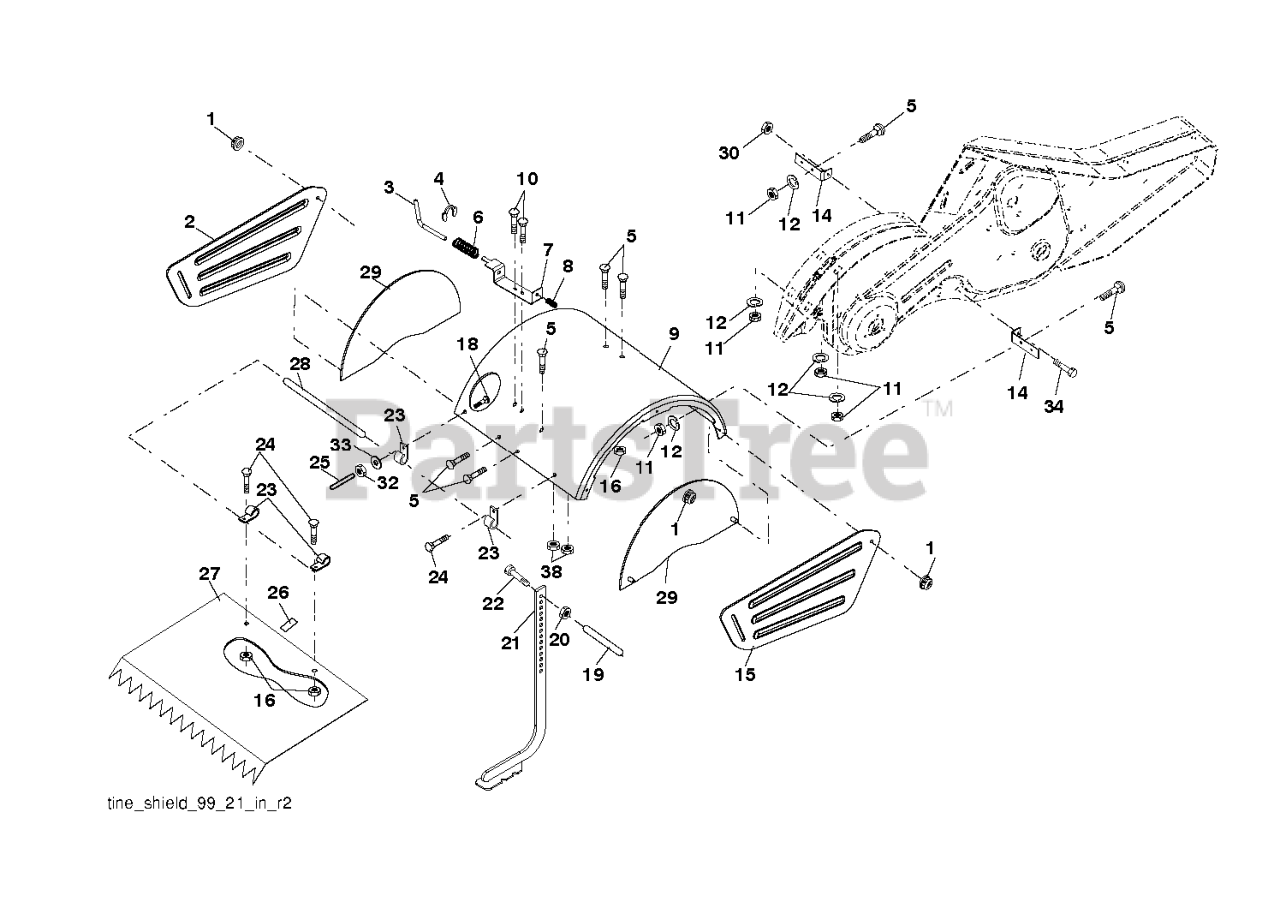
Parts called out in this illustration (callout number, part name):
1	NUT LOCK HEX FLANGE 5/16-18
2	SHIELD.SIDE.OUTER.LH.ORANGE
3	STAKE PIN TI
4	RING, KLIP
5	BOLT, RDHD SQNK 5/16-18 X 3/4
7	BRACKET.LATCH.STAKE.3.20.BLACK
8	SPRING CRT
9	SHIELD.TINE.TILLER.ORANGE
12	WASHER.LOCK.HVY.HLCL.SPR.5/16
14	BRACKET.TINE.SHIELD.TILLER
15	SHIELD.SIDE.OUTER.RH.ORANGE
16	NUT T
20	NUT.HEX.3/8-16UNC
21	STAKE.ASM.DEPTH
22	BOLT.375-16
25	VINYL CAP TI
26	PAD IDLER TI
27	SHIELD.PNT.LEVELING.ORANGE.668
28	PIN, HINGE
29	SHIELD.ASM.PNT.SIDE.ORANGE.668
30	LOCKNUT-FLANGE 5/16-18
32	NUT
33	LOCKWASHER
34	Bolt Hex Flanged 5/16-18 Unc x 2
38	NUT
